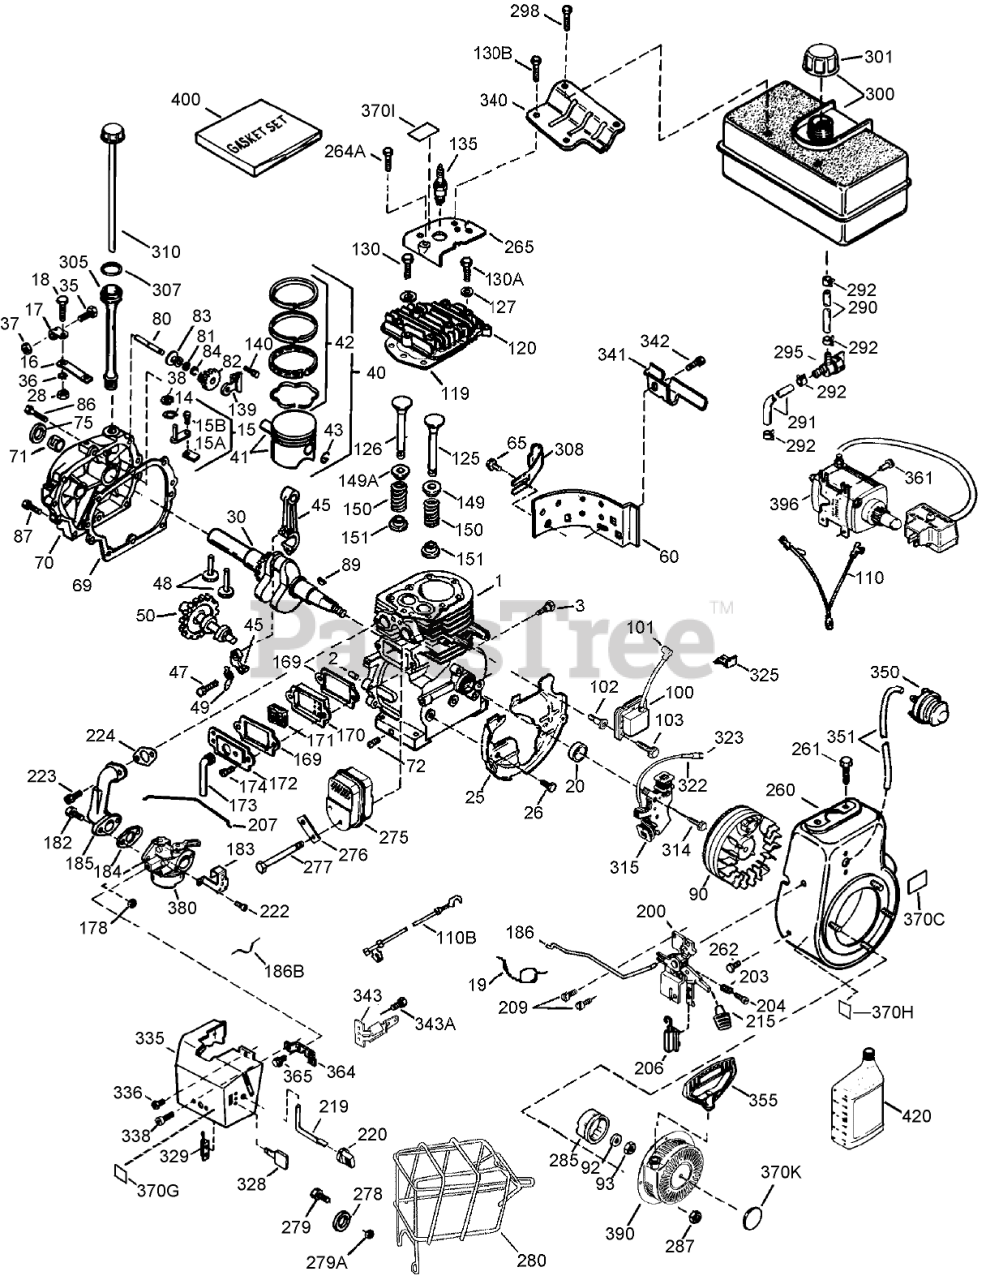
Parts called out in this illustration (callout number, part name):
264A	Screw (1/2-20x5/8)
265	Cover-Head, Cylinder (Black)
275	Muffler
276	Plate-Locking
277	Screw (5/16-18x4-3/16)
278	Washer-Flat
279	Screw (10-16 x 47/64)
279A	washer-Lock
280	Muffler Heat Shield ASM (Includes 278, 279, 279A)
285	Cup-Starter
287	Nut and Lock Washer (1/4-28)
290	Line-Fuel (8.62)
291	Line-Fuel
292	Clamp-Line, Fuel
295	Valve-Shut Off, Fuel (Includes 292)
298	Screw (1/4-15x7/8)
300	Tank-Fuel (Includes 292, 301)
301	Cap-Fuel (Black) (1-1/2 I D)
305	Tube-Fill, Oil
307	O-Ring
308	Clip-Tube, Fill
310	Dipstick
314	Screw (1/4-20 x 3/4)
315	Coil-Alternator, 18 Watt (Includes 322, 323)
322	Body-Connector
323	Terminal
325	Clip-Wire
328	Key-Ignition
329	Terminal
335	Cover-Carburetor (Black)
336	Screw (10-32x1/2)
338	Screw (10-32 x 3/8)
340	Bracket-Tank, Fuel (Black)
341	Bracket-Tank, Fuel
342	Screw (1/4-20x19/32)
343	Bracket-Switch, Key (Includes 343A)
343A	Screw (8-32 x 23/64)
350	Primer ASM
351	Line-Primer (12in)
355	Handle-Starter, Mitten Grip
361	Screw (T-30, 1/4-20x15/32)
364	Bracket-Cover, Carburetor
365	Screw (8-32x27/64)
370C	Decal-Primer, International Symbol
370G	Decal-Instruction
370H	Decal-Speed Control and Choke
370I	Decal-Warning (Bilingual)
370K	Decal-Tecumseh Logo for Top of Recoil Starter
380	Carburetor (Includes 184)
390	Starter-Rewind (Note: This engine could have been built with starter 590733)
396	Electric Starter Motor ASM (220 Volt)
400	Gasket Set (Includes 69, 119, 169, 184, 224)
420	Oil-Engine, S A E 5W30
